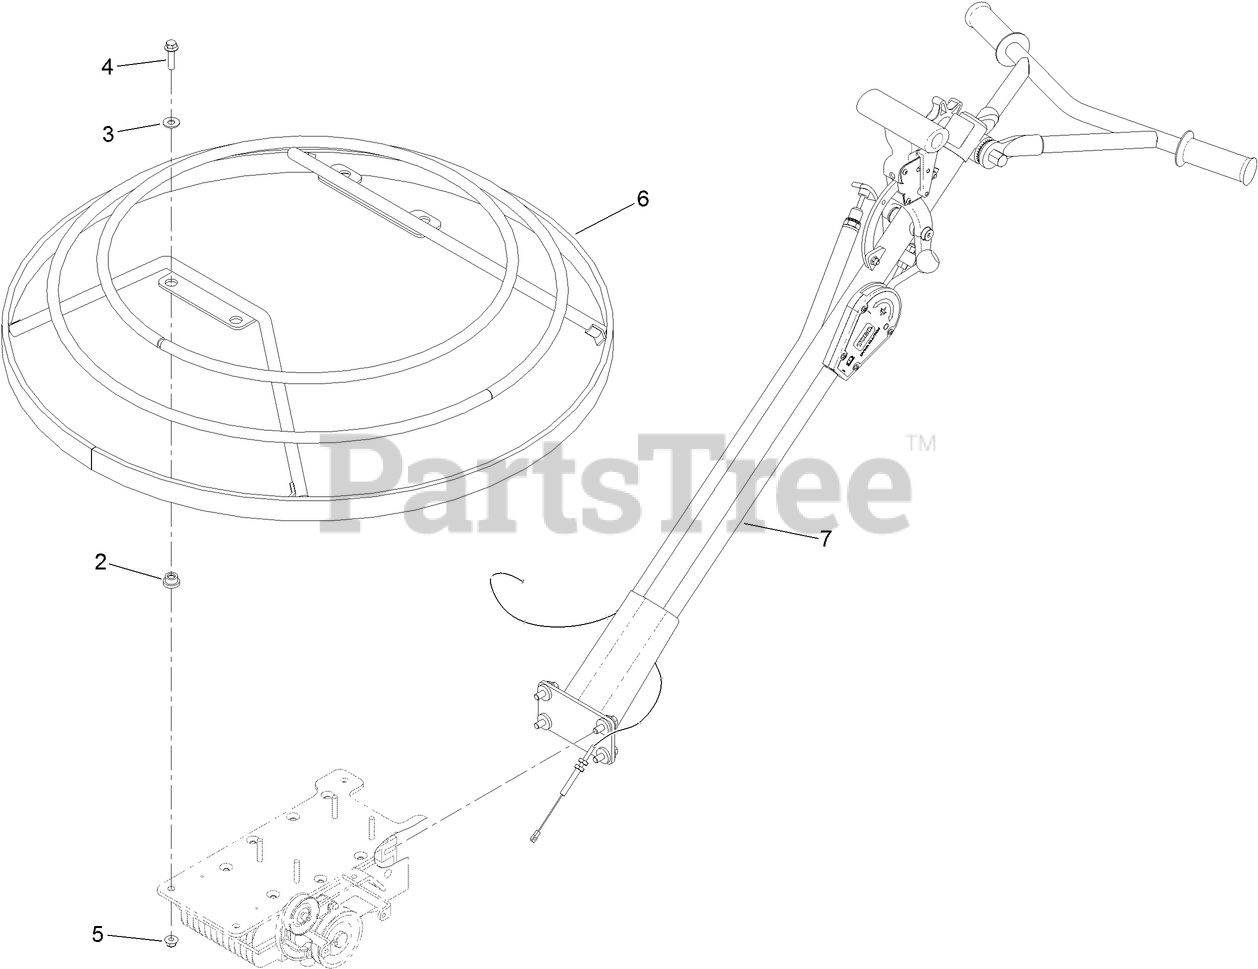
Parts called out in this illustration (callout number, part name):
2	MOUNT-SHOCK
3	WASHER-FLAT
4	SCREW-HHF
5	NUT-HF, NI
6	GUARD-STATIONARY
7	PRO-PITCH HANDLE ASM
